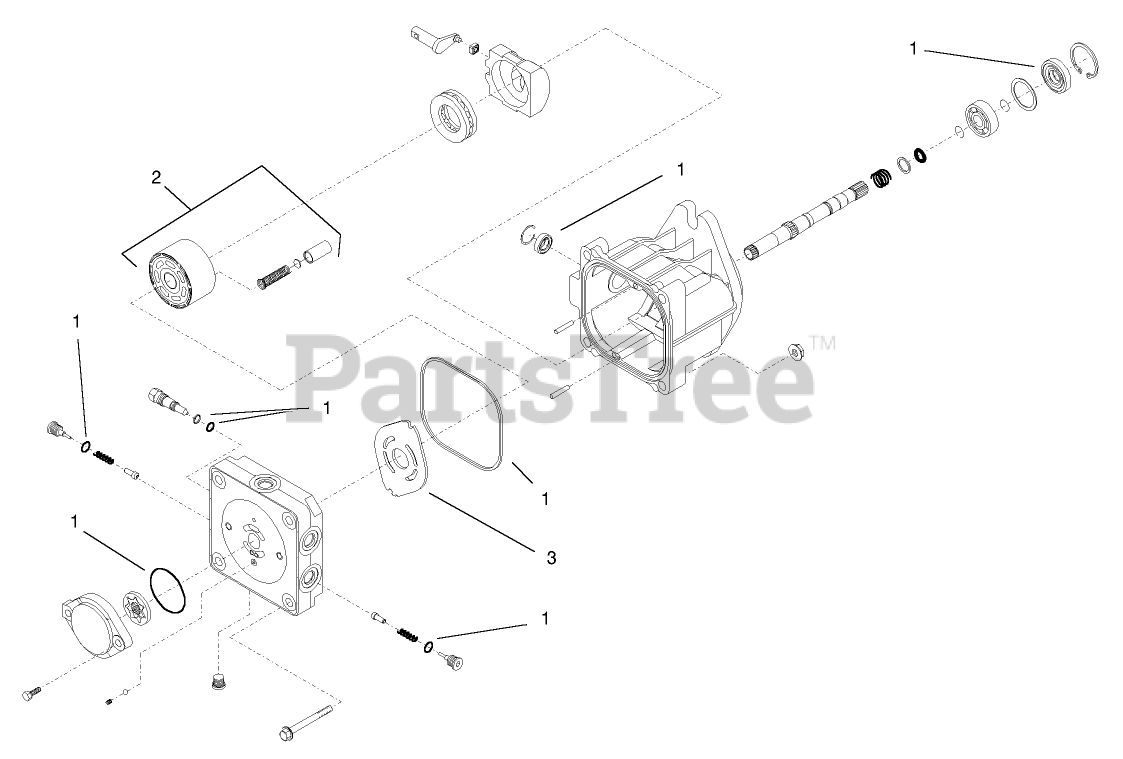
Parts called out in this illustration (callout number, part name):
1	OVERHAUL SEAL KIT
2	KIT-BLOCK, CYLINDER
3	PLATE-VALVE
